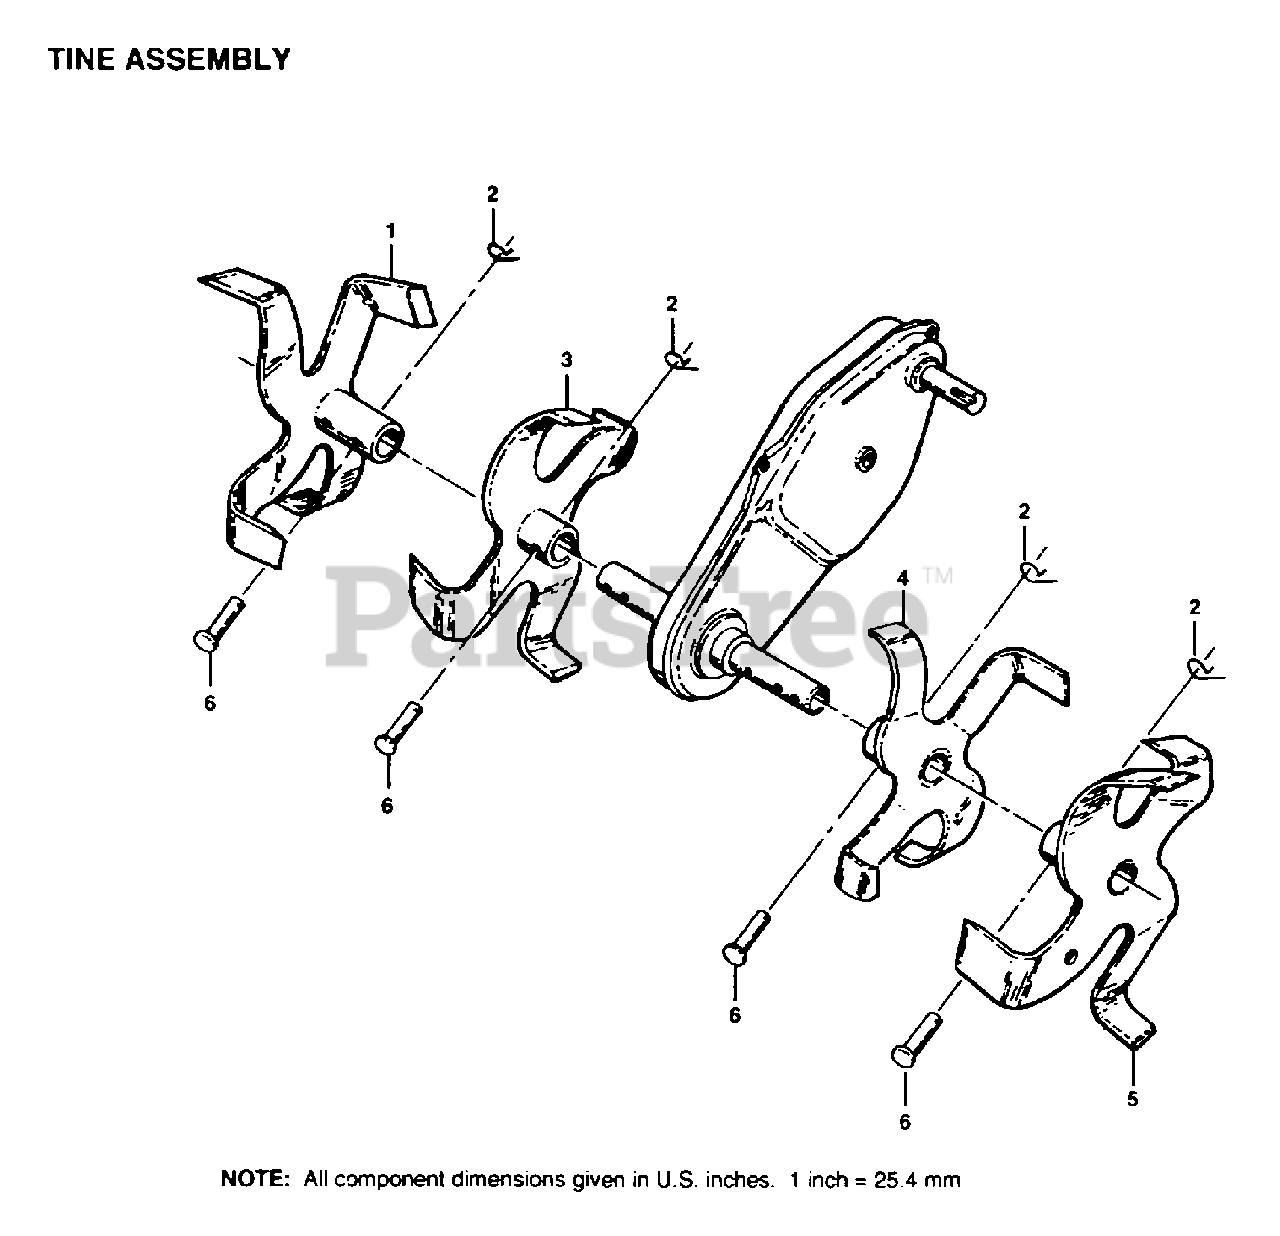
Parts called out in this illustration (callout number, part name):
1	TINE OUTER RH T
2	RETAINER.SPRING
4	TINE.INNER.LH
5	TINE.OUTER.LH.T
6	RIVET.PAN HD.1.75
